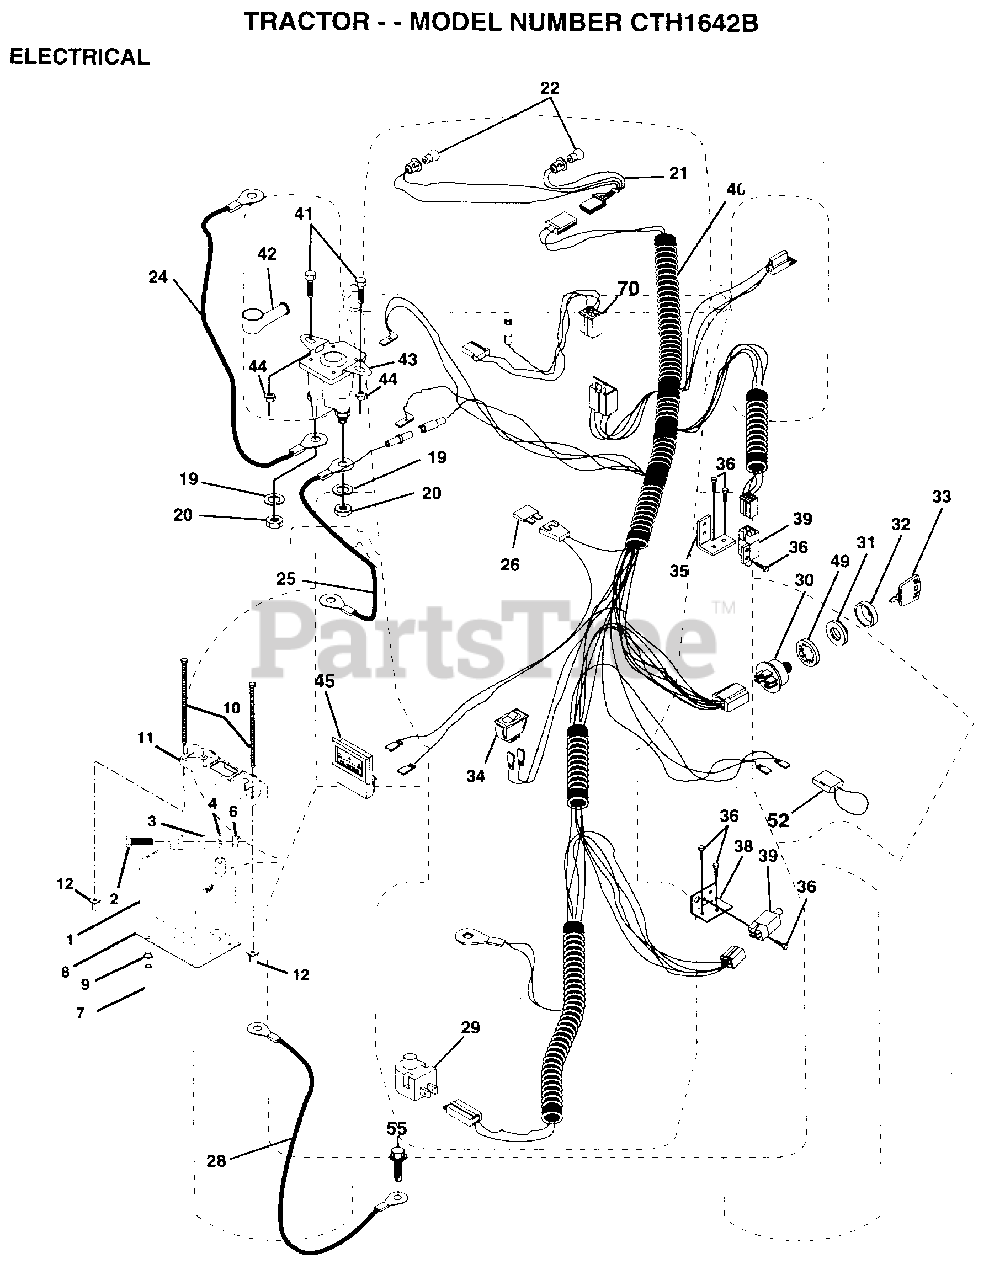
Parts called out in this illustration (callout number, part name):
2	BOLT LT
3	WASHER
4	LOCKWASHER
7	"DRAIN TU T, BATT"
8	"TRAY T, BATTERY"
9	HOSE CLAMP T
20	NUT
21	HARNESS.ASM.HDLIG
22	HEADLAMP BULB
24	"CABLE T, BATTERY"
25	CABLE.6GA.22W/16W
26	FUSE HYT
28	CABLE.GRND.6GA.21
29	SWITCH SEAT
32	COVER KEY SWITCH
33	KEY MLD GEN DELTA
34	SWITCH LT
35	BRACKET LT
36	SCREW
38	BRACKET SWITCH IN
39	SWITCH INTERLOCKT
40	HARNESS.IGN.MECH.
41	BOLT HXHD FIN
44	NUT HXKEP 1/4X20
49	LOCKWASHER
52	PROTECTION LOOP
55	SCREW LT
70	HARNESS ENG DUAL
